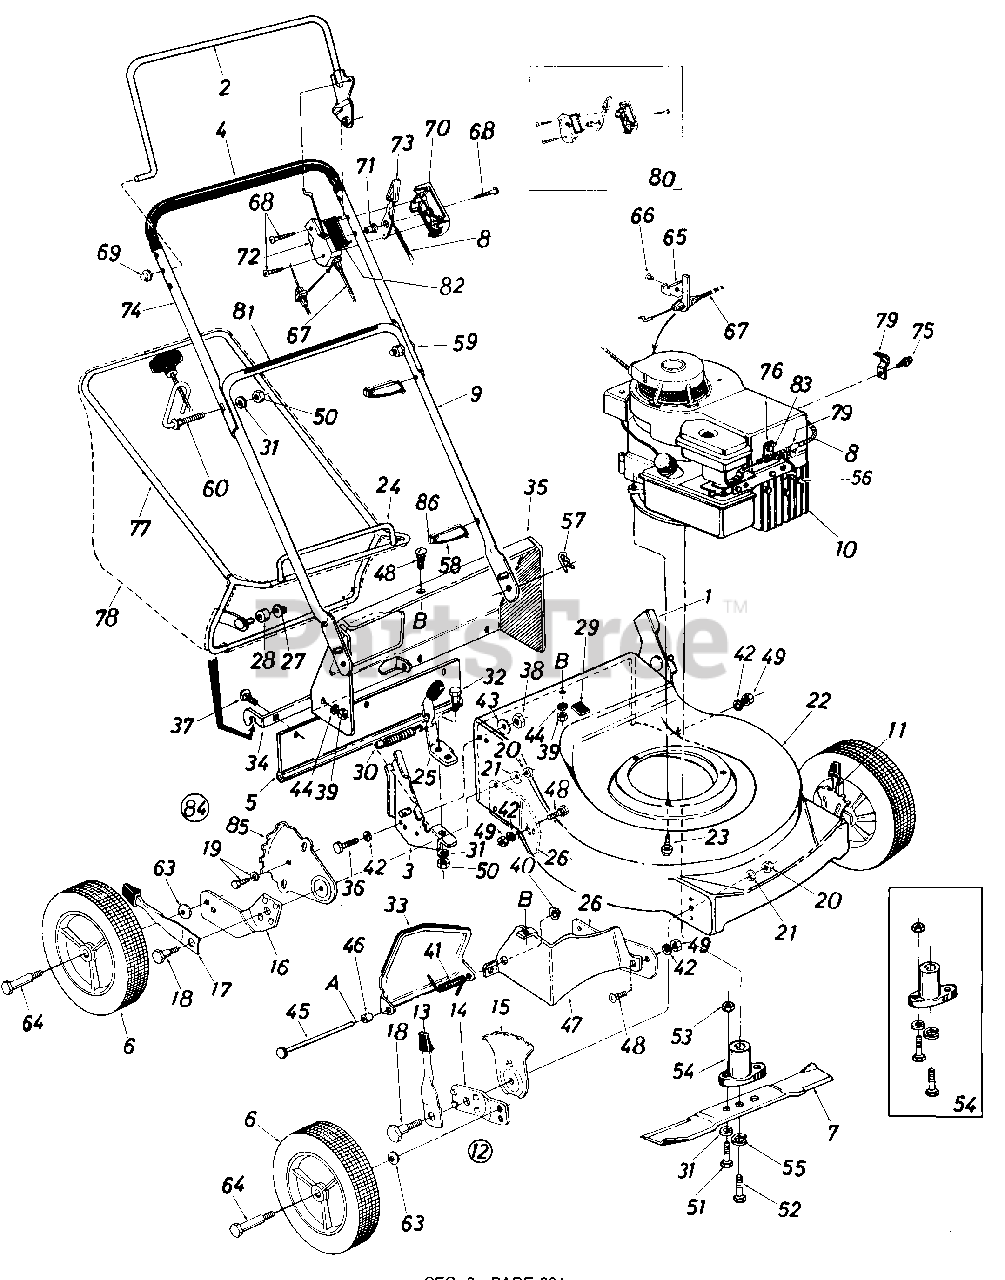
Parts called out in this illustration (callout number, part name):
1	Handle Brkt. Ass'y. L.H.
2	Control Handle Ass'y. L.H.
3	Handle Brkt. Ass'y. R.H.
4	Grip
5	Rear Flap Ass'y.
6	Wheel Ass y.
7	21" Blade
8	Throttle Wire 58" (Black)
9	Lower Handle
10	Engine
11	Front L.H. Height Adj. Ass'y.
12	Front R.H. Height Adj. Ass'y.
13	Spring Lever Ass'y. w/Knob
14	Front Pivot Bar
15	Front Index Plate
16	Rear Pivot Bar R.H.
17	Spring Lever w/Knob
18	Shld. Bolt .50" Dia. x .375
19	Hex Wash. Hd. Tap Scr. 1/4 x.62" Lg.
20	Hex Nut 3/8-16 Thd.
21	Bell-Wash. .39" I.D. x .38"
26	Baffle
27	Push Nut 3/8" Rod
28	Plastic Roller
29	Plug Catcher Hook Slot
30	Tension Spring
31	L-Wash. 5/16" I.D.
32	Shld. Bolt .437" Dia. x .162
33	Chute Door
34	Grass Catcher Hitch Brkt.
35	Rear Discharge Deck Section
36	Hex Bolt 1/4-28 X .75" Lg.
37	Carr. Bolt 1/4-20 X .75" Lg.
38	Hex Nut 1/4-28 Thd.
39	Sems Nut 1/4-20 Thd.
40	Push Nut 1/4" Rod
41	Torsion Spring
42	L-Wash. 1/4" I.D.
43	Bell-Wash. 1/4" I.D. x .88"
44	Fl-Wash. .285" I.D. x 1.25"
45	Hinge Pin .250" Dia. x 7.25"
46	Spacer .262" I.D. x .31" O.D. x .58
47	Rear Baffle
48	Carriage Bolt 1/4-20 x .50"
49	Hex Nut 1/4-20 Thd.
50	Hex Nut 5/16-18 Thd.
51	Hex Bolt 5/16-24 x 1.00" Lg. (Grade 5)
52	Hex Bolt 3/8-24 x 2.25" Lg. (Grade 5)
53	Hex Nut 5/16-24 Thd.
54	Blade Adapter Kit
55	L-Wash. 3/8" I.D. H.D.
56	Spark Plug Boot
57	Intern. Cot. Pin 5/16" Dia.
58	Cable Tie
59	Curved Carriage Bolt 5/16-18 x 1.38" Lg.
60	Rope Guide Bolt
63	Bell-Wash. .400" I.D. x .88" O.D. x .060
64	Axle Bolt
65	Cable Bracket
66	Pop Rivet .156" Dia. x .379
67	Brake Control Cable 43"
68	Truss Mach. Hd. "B" Tap Scr. #12 x 1.50" Lg.
69	Cap Speed Nut 5/16" Rod
70	Control Panel Half
71	Control Disc Pin
72	Clutch Panel Half
73	Throttle Control Lever
74	Upper Handle
75	Hex "B" Tap Scr. #10 x .38"
76	Casing Clamp
77	Grass Catcher Upper Frame
78	Grass Bag
79	Casing Clamp
80	Control Housing Comp.
81	Instruction Label Handle
82	Control Label Throttle
83	Hex Wash. Hd. AB-Tap Scr. #8 x .38" Lg.
84	Rear Height Adj. Ass'y. R.H.
85	Rear Index Plate
86	Cable Anchor
